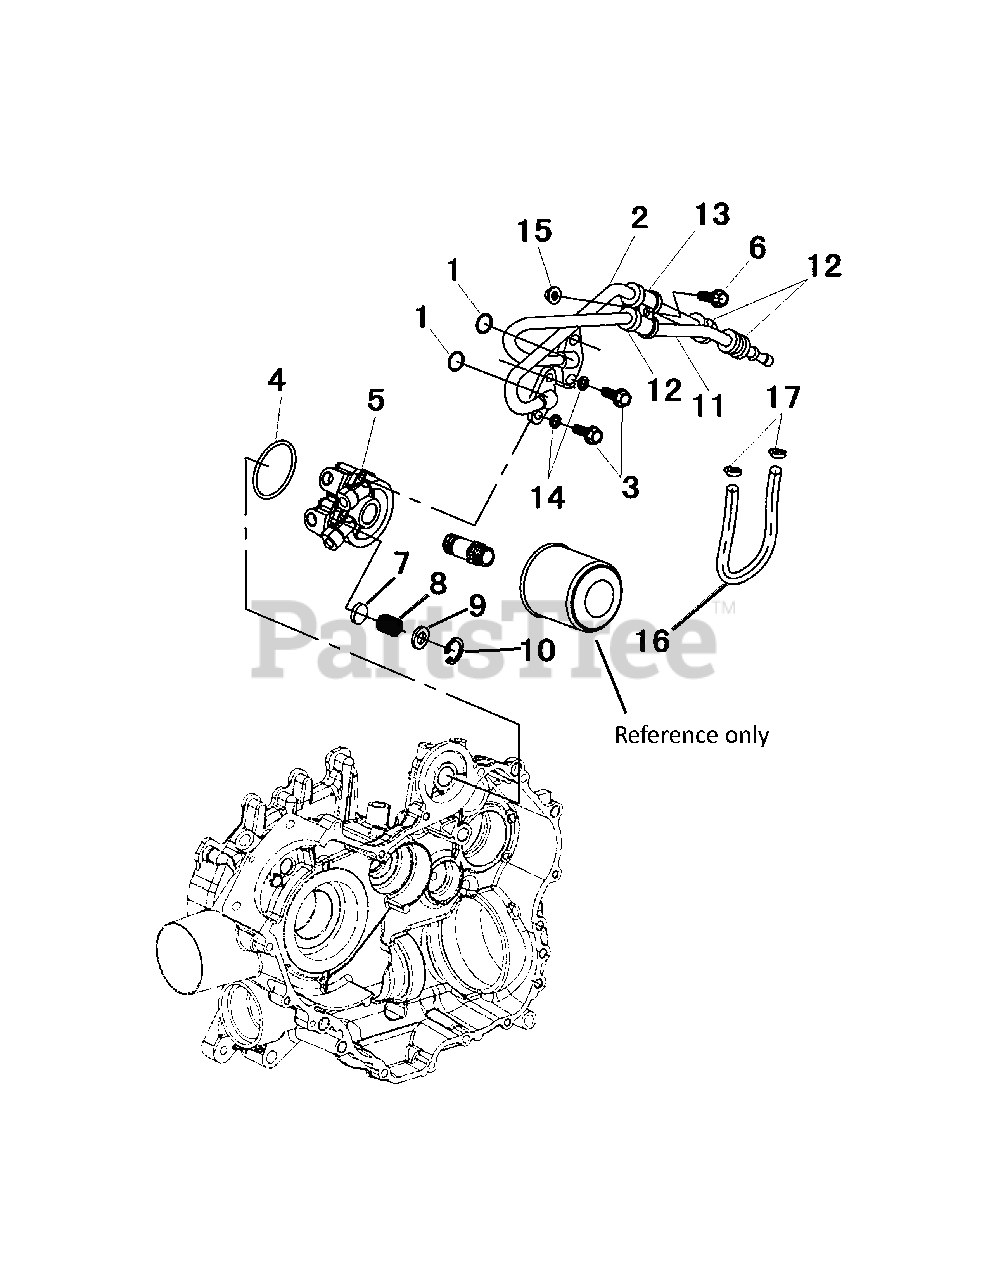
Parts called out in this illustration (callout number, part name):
2	Oil Pipe-V/UTV
3	Flangebolt M6X20
4	O-Ring 57.2X3
6	Flangebolt M6X12
8	Spring-Relief Valve 0.8×7.9×19
9	Washer 6×11.8×1
11	Oil Pipe-V/UTV
12	Protecting Jacket, Oil Pipe
13	Hoop, Oil Pipe
15	Nut M6 (DarkGreen)
16	Hose
